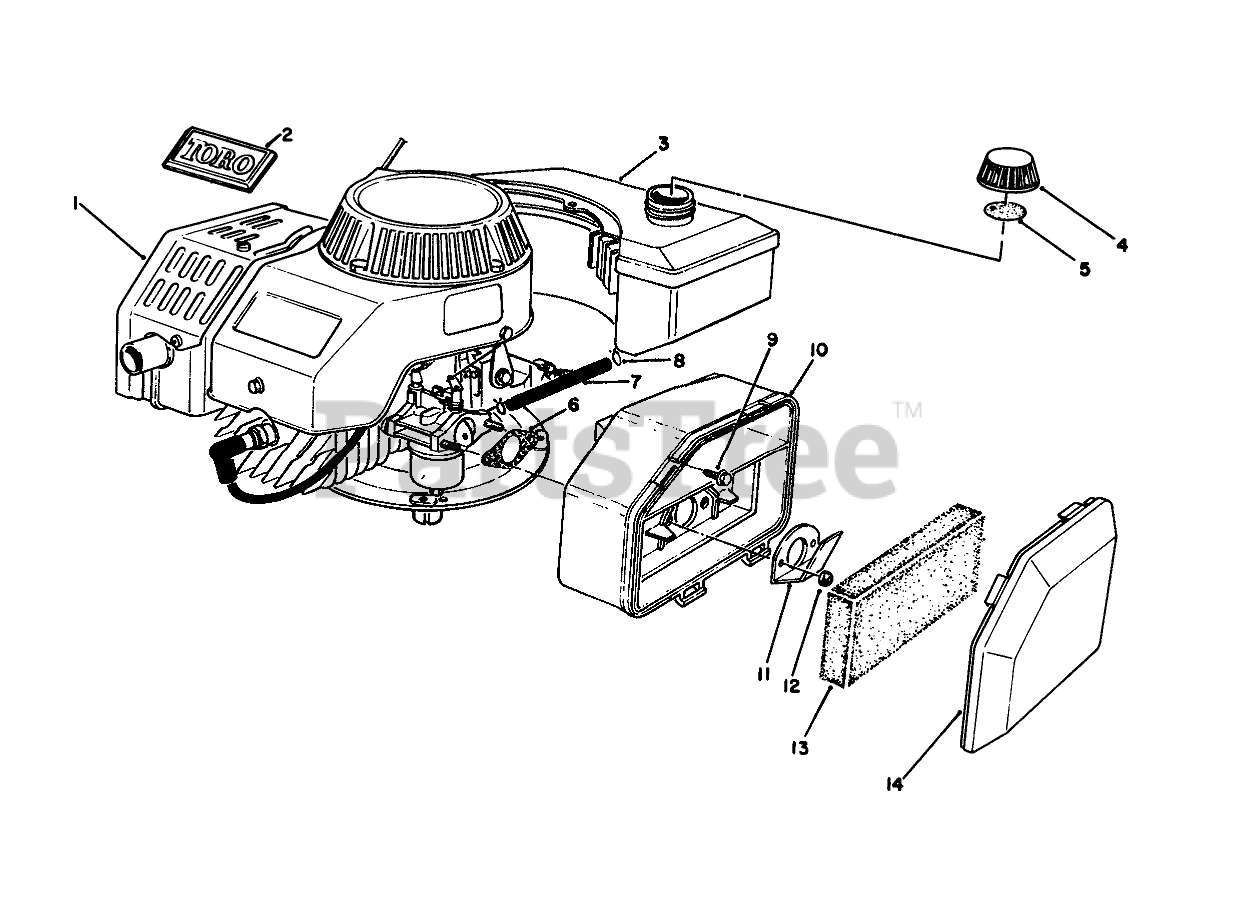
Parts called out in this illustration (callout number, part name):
1	Engine
2	TORO LOGO PLT
3	Gas Tank Assembly
4	Gas Cap Assembly (Incl. Ref. #5)
5	GAS CAP GASKET
6	GASKET-AIR CLEANER
7	FUEL LINE
8	CLAMP-HOSE
9	SCREW-HH
10	AIR CLEANER
11	SPIT BACK DEFLECTOR
12	NUT-LOCK
13	FILTER
14	AIR CLEANER COVER
